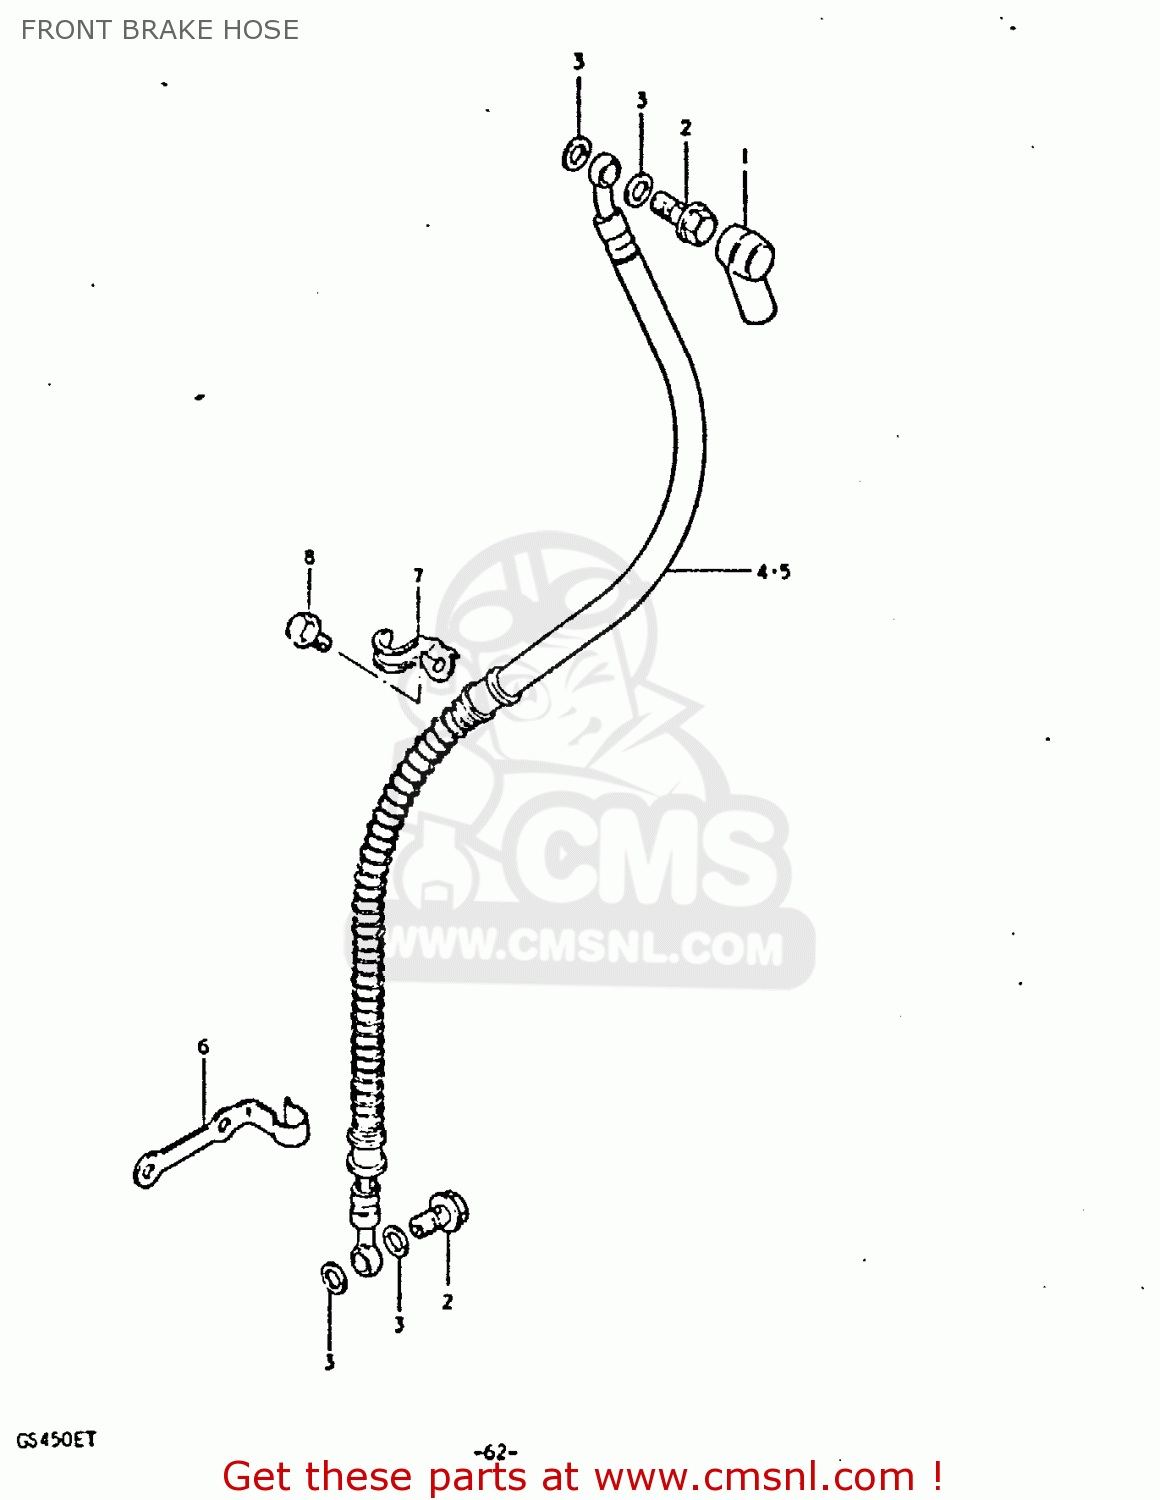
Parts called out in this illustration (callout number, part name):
1	BOOT,MASTER CYLINDER
2	BOLT,UNION
3	WASHER
4	HOSE,FRONT BRAKE
5	HOSE,FRONT BRAKE
6	GUIDE,BRAKE HOSE NO.2
7	GUIDE,BRAKE HOSE NO.3
8	BOLT
